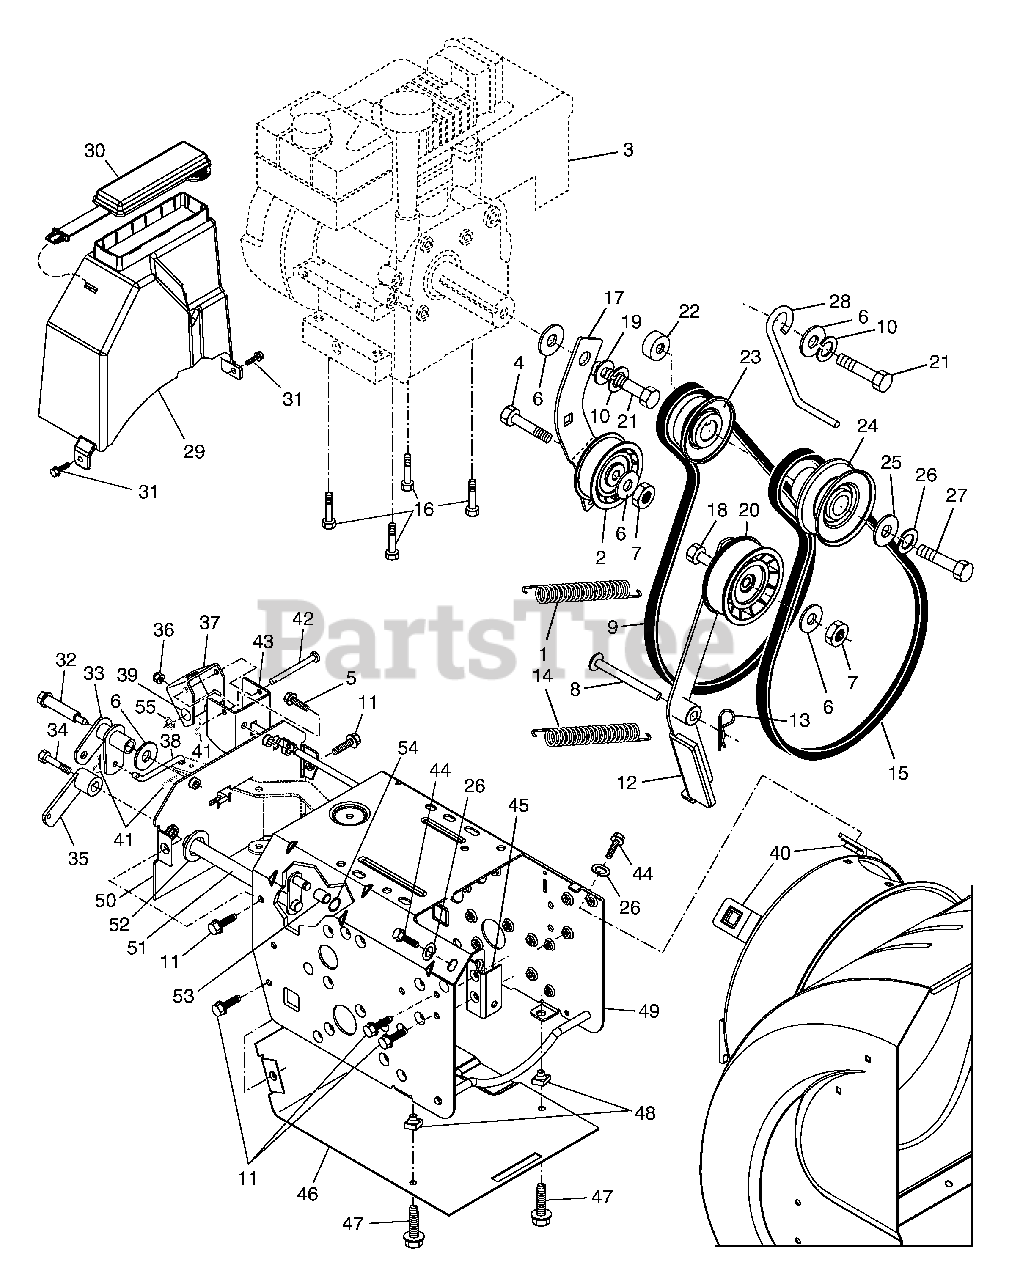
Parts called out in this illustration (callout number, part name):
1	Spring, Traction Idler
2	Pulley, Idler (2-1/4)
4	Screw, Hex Head 5/16-18 x 1-1/4
5	Screw, Hex Washer Head 5/16-18 x 3/4
6	Washer, Flat
7	Nut, Jam, Lock 5/16-18
8	Pin, Idler Pivot
9	V-Belt, Traction Drive
10	Washer, Lock 5/16
11	Screw, Hex Washer Head 5/16-18 x 1/2
12	Impeller Idler Arm Assembly
13	Retainer, Hairpin
14	Spring, Brake
15	V-Belt, Impeller Drive
16	Screw, Hex Head 3/8-16 x 1-1/4
17	Arm, Idler
18	Screw, Hex Head 5/16-18 x 1-1/2
19	Bushing, Idler Pivot
20	Pulley, Idler (2-3/4)
21	Screw, Hex Head 5/16-24 x 1
22	Spacer, Engine Pulley
23	Pulley, Engine, Traction Drive
24	Pulley, Engine, Impeller Drive
25	Washer, Flat 3/8
26	Washer, Lock, Helical
27	Screw, Hex Head 3/8-24 x 1-3/8
28	Guide, Belt
29	Cover, Belt
30	Cover, Toolbox
31	Screw, Hex Head 1/4-20 x 1/2
32	Bolt, Shoulder 5/16-18
33	Bellcrank Shifter
34	Screw, Hex Head 1/4-28 x 3/4
35	Arm, Auger Control
36	Nut, Lock 5/16-18
37	Bellcrank Assembly
38	Link, Speed Control
39	Trunnion, Clutch
40	Nut, Cage 3/8-16
41	Hairpin, Cotter 3/32 x 1/2
42	Pin, Bellcrank
43	Bracket, Bellcrank
44	Screw, Hex Head 3/8-16 x 1-1/2
45	Pivot Bracket, Impeller Idler Arm
46	Pan, Frame Bottom
47	Screw, Hex Head 5/16-18 x 3/4
48	Nut, Speed 5/16-18
49	Frame Assembly
50	Plate, Frame End
51	Shaft, Auger Control
52	Washer, Hardened
53	Roller
54	Ring, Crescent
